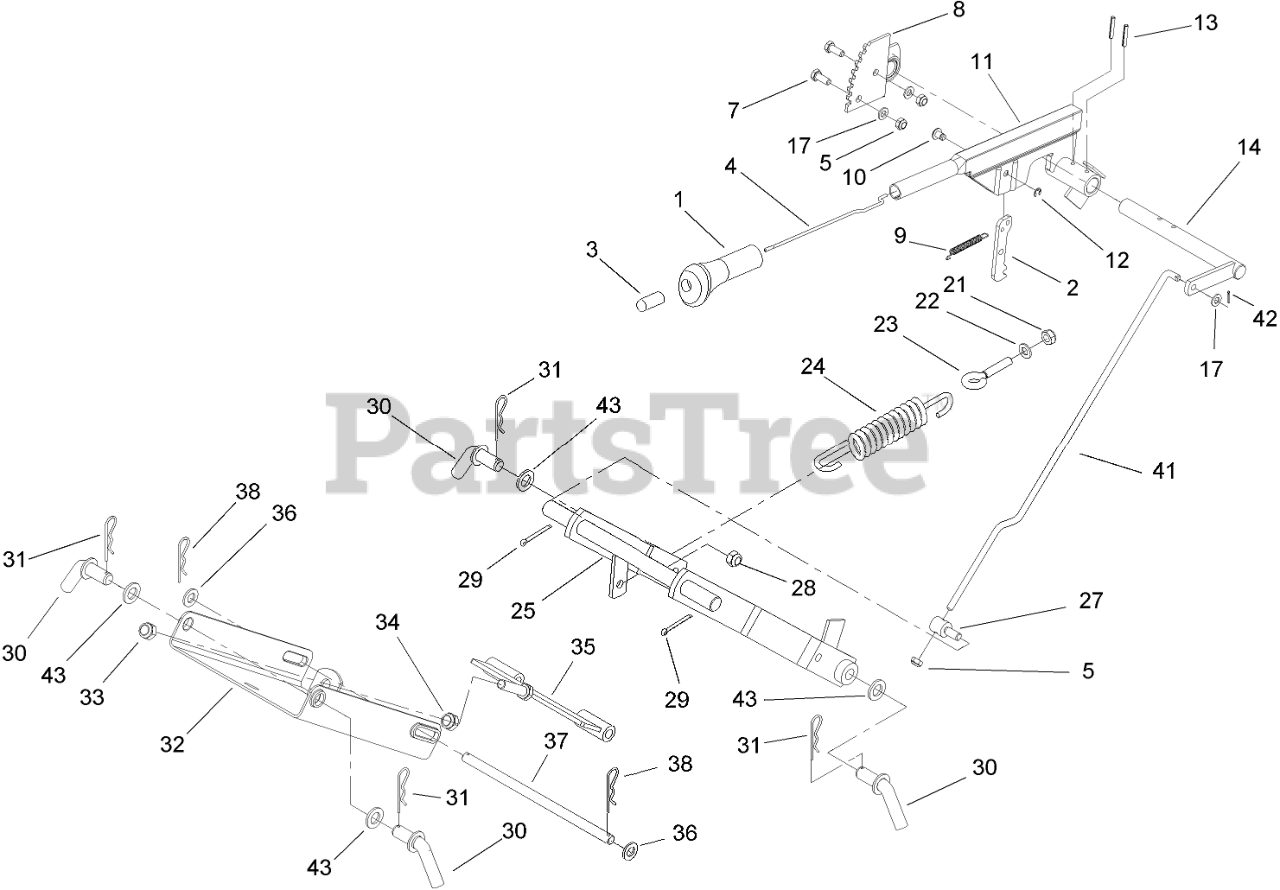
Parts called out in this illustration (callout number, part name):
1	GRIP-HANDLE
2	RATCHET-PLATE, PIVOT
3	BUTTON-PLUNGER
4	ROD-CONNECTION
5	NUT-LOCK, NI
7	SCREW-HH
8	SEGMENT-GEAR
9	SPRING
10	PIN-LEVER, ARM
11	LEVER-ARM, HEIGHT ADJ.
12	CLIP-PIN
13	PIN-SPRING
14	SHAFT-HEIGHT ADJ.
17	WASHER-PLAIN
21	NUT-LOCK, NI
22	WASHER-FLAT
23	BOLT-EYE
24	SPRING-LIFT
25	PIVOT ARM ASM
27	PIN-LIFTING
28	NUT-LOCK, NI
29	PIN-COTTER
30	PIN-BENT
31	PIN-HAIR
32	SUSPENSION-MOWER DECK, FRONT
33	NUT-LOCK
34	NUT-HEX
35	HOLDER-FRONT
36	WASHER-FLAT
38	PIN-HAIR
41	ROD-HEIGHT, ADJ.
42	PIN-COTTER
43	Washer-Hose
